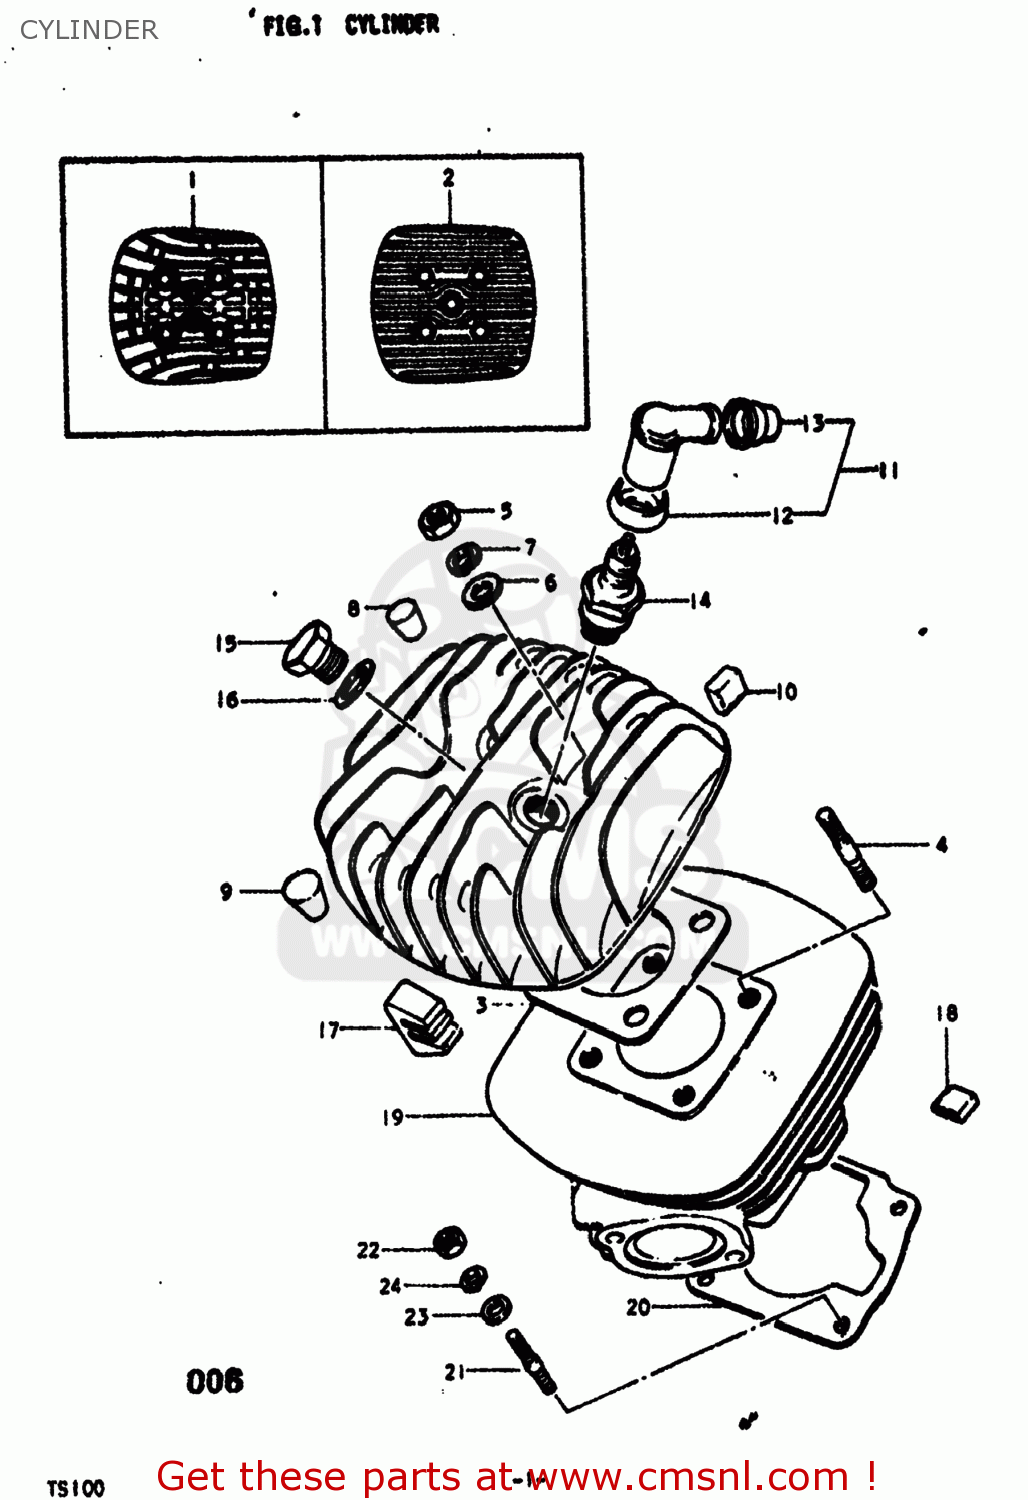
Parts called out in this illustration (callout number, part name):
1	HEAD,CYLINDER
2	HEAD,CYLINDER
3	GASKET,CYLINDER HEAD (MCA)
4	STUD BOLT (L:45)
5	NUT
6	WASHER
7	LOCK WASHER
8	PAD,CYLINDER HEAD
9	PAD,CYLINDER HEAD
10	PAD,CYLINDER
11	CAP,SPARK PLUG
12	SEAL,SPARK PLUG
13	SEAL,SPARK PLU
14	SPARK PLUG
15	PLUG
16	GASKET(14X19.2X2) (NAS)
17	PAD,CYLINDER
18	PAD,CYLINDER
19	CYLINDER
20	GASKET,CYLINDER (MCA)
21	STUD 8X25
22	NUT
23	WASHER
24	LOCK WASHER
